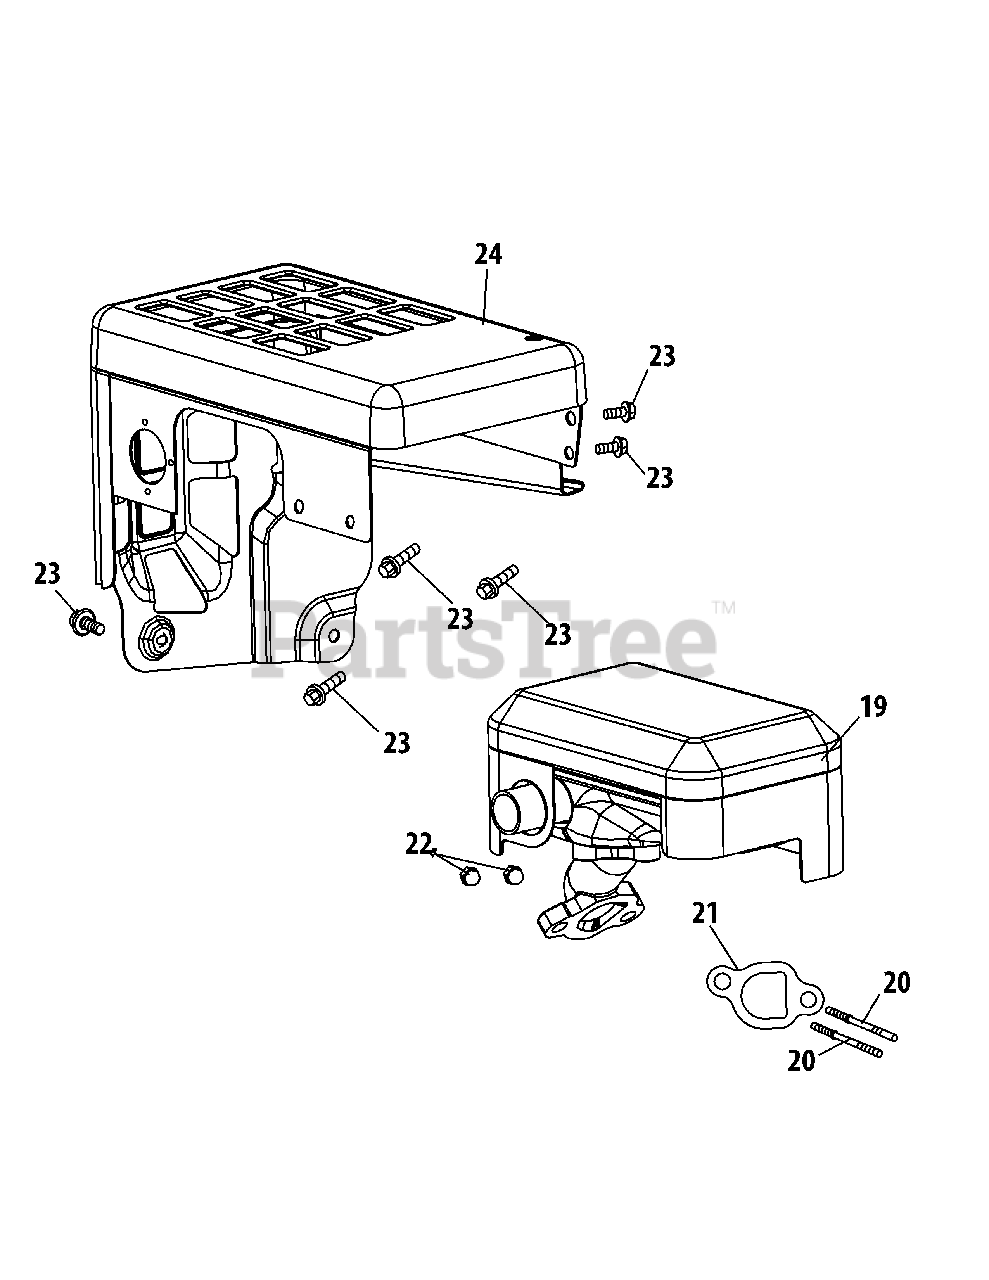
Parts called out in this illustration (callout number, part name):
19	Muffler Assembly
20	Muffler Stud
20	Muffler Stud Kit
21	Muffler Gasket
22	Nut - M8
23	Bolt - M6 X 12 Zin
24	Muffler Shroud
